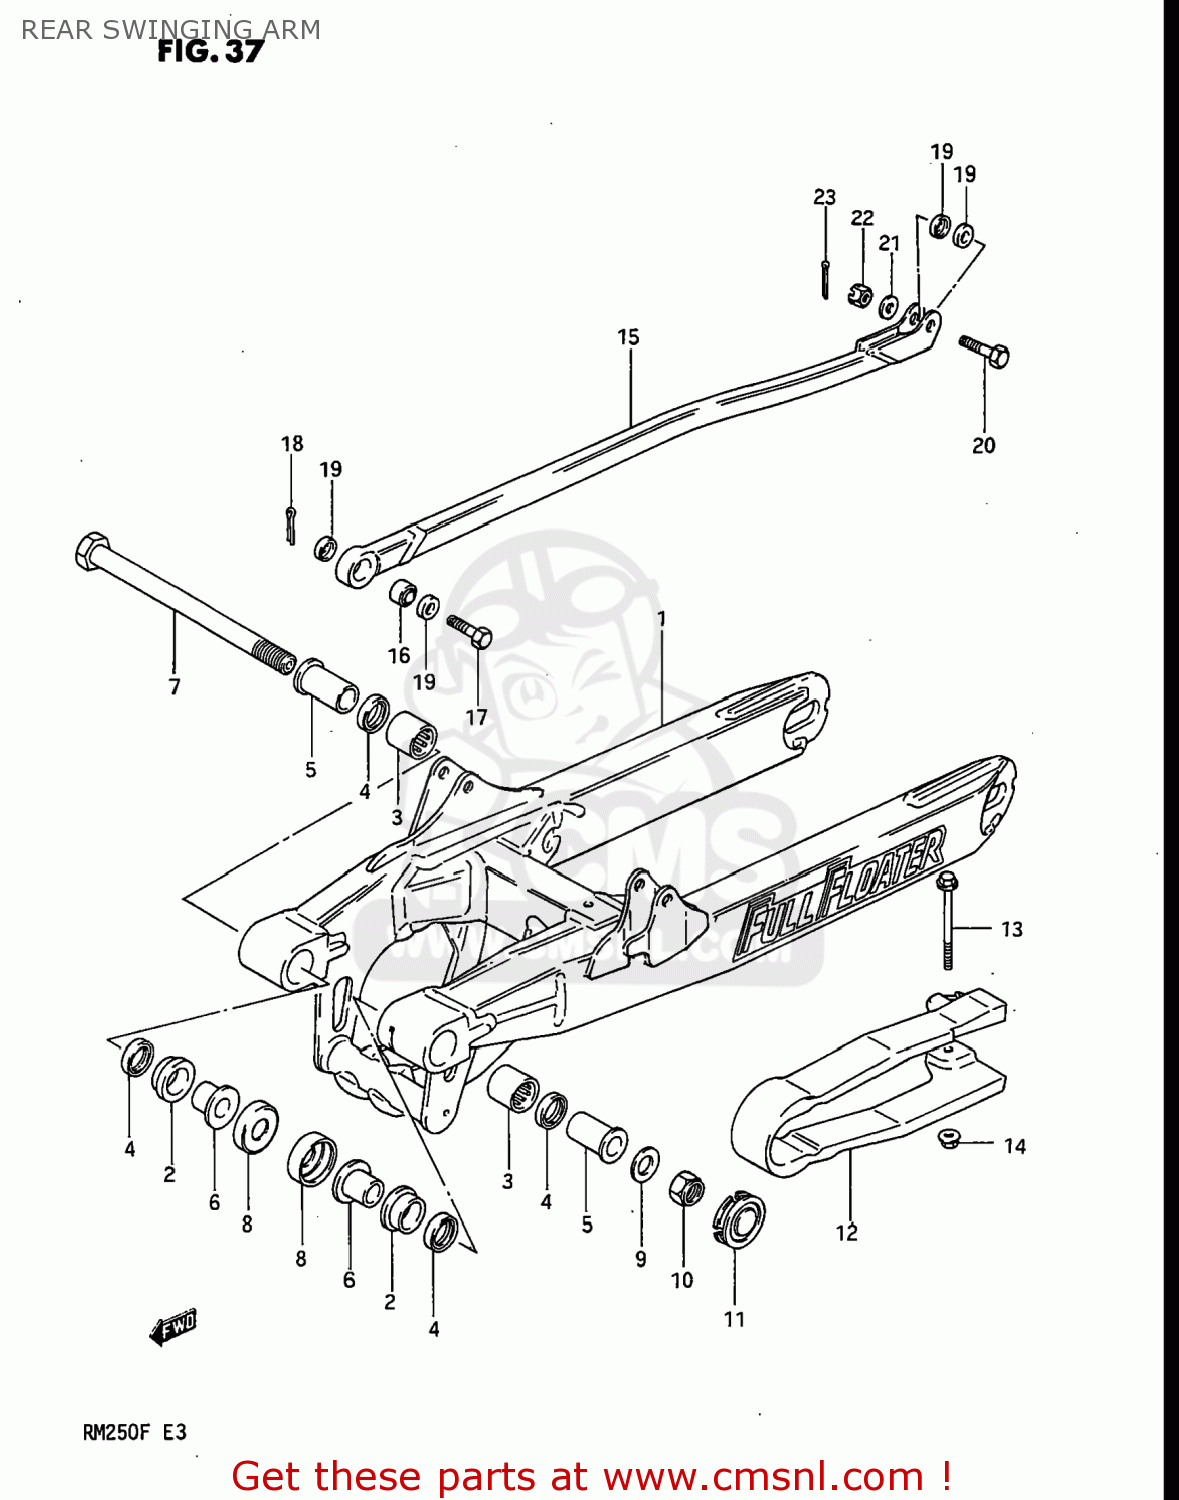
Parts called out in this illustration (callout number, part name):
1	SWING ARM ASSEMBLY,REAR
2	BUSHING,REAR SWING ARM PIVOT
3	BEARING(20X27X20)
4	OIL SEAL
5	SPACER,RR SWINGING ARM PIVOT
6	SPACER,RR SWGARM PIVOT INNER
7	SHAFT,PIVOT
8	COVER,RR SWGARM DUST SEAL
9	WASHER(15X29X3.6)
10	NUT
11	CAP
12	BUFFER,CHAIN TOUCH DEFENSE
13	BOLT (6X70)
14	NUT
15	LINK,REAR TORQUE
16	SPHERICAL BEARING,TORQUE
17	BOLT 8X28
18	PIN
19	20
20	BOLT 8X29.5
21	WASHER
22	NUT 8MM
23	PIN 20X20
